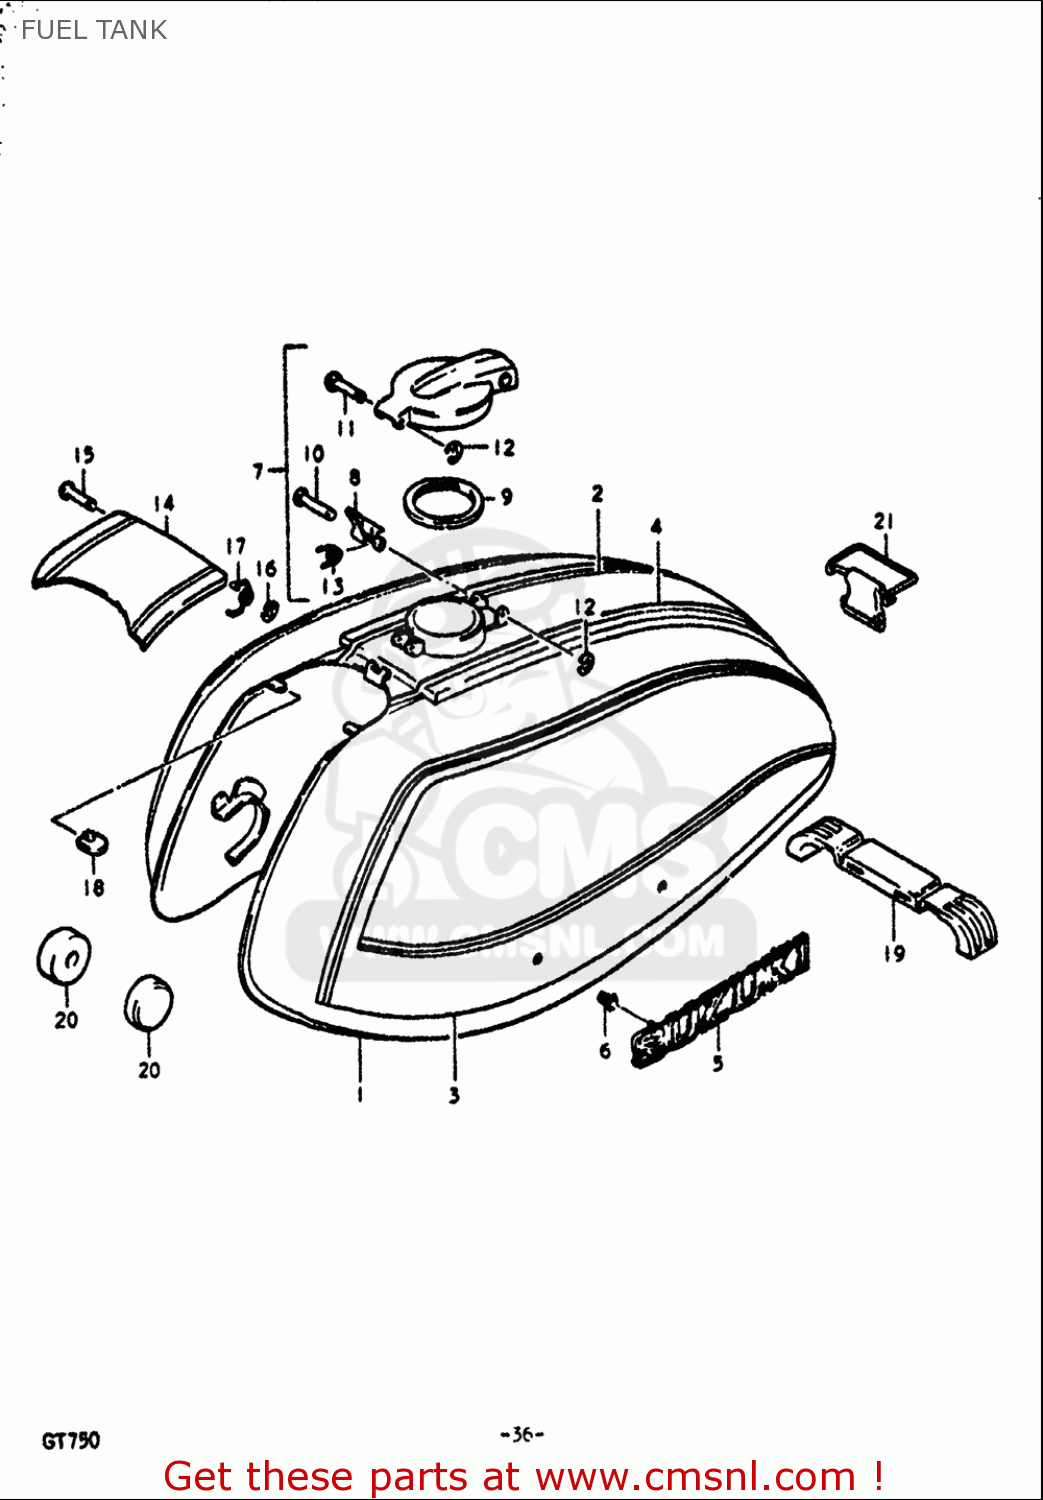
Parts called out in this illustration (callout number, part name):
6	NUT
8	LEVER
10	PIN
12	E RING
13	SPRING
17	SPRING
19	CUSHION
20	CUSHION
21	BAND
